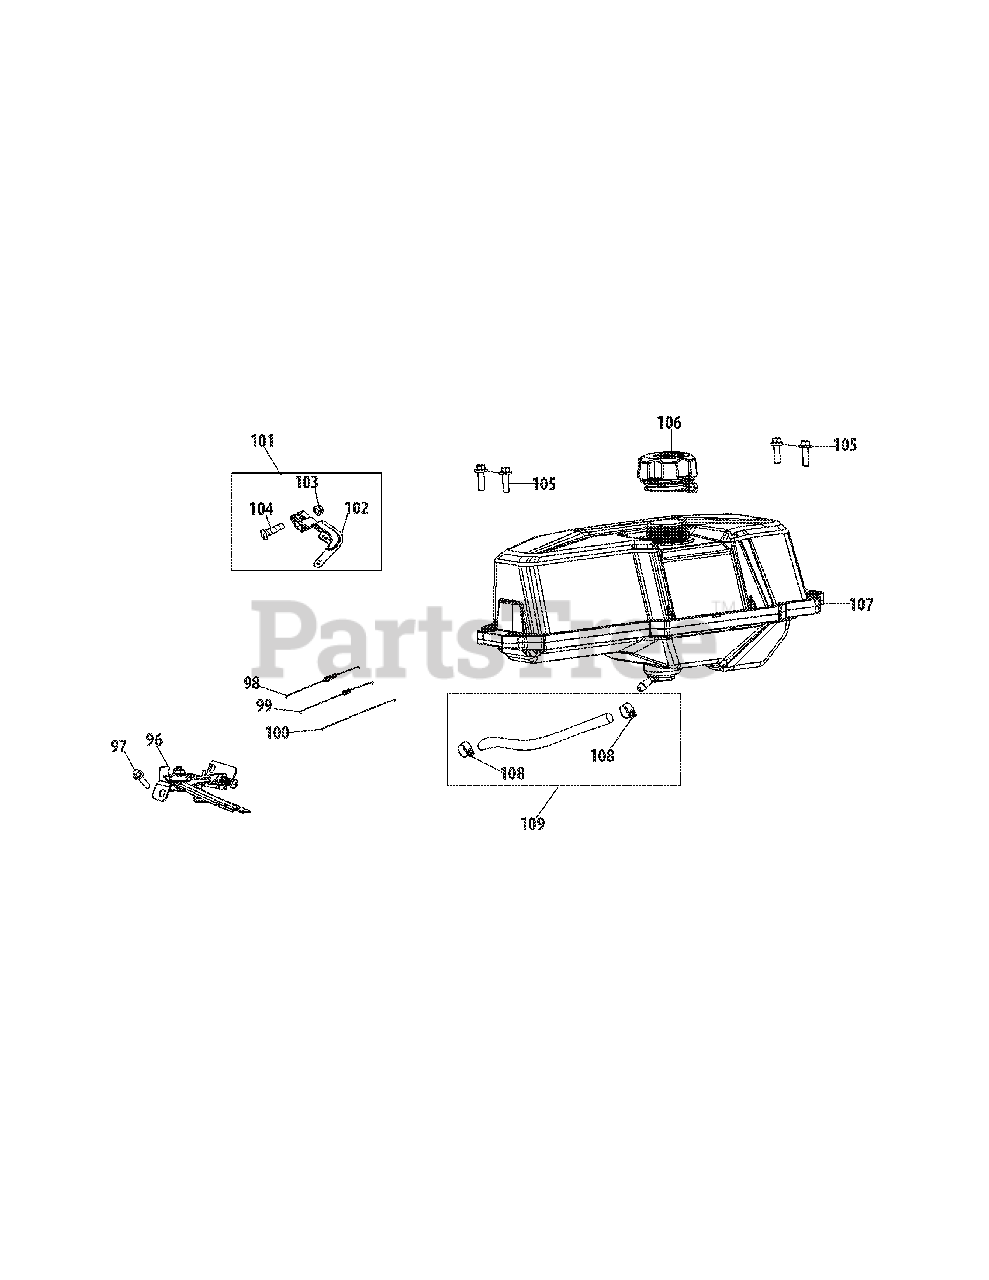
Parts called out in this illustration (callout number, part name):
96	GOVERNOR GEAR BRACKET ASSY
97	FLANGE BOLT M6×12
98	GOVERNOR SPRING
99	IDLE SPRING
100	ROD GOVERNOR
101	GOVERNOR LEVER
102	GOVERNOR LEVER
103	FLANGE NUT M6
104	BOLT M6×21
105	BOLT M6×22
106	FUEL CAP
107	FUEL TANK
108	CLAMP, FUEL HOSE
109	FUEL HOSE F6.3 X 12.5 X 133
